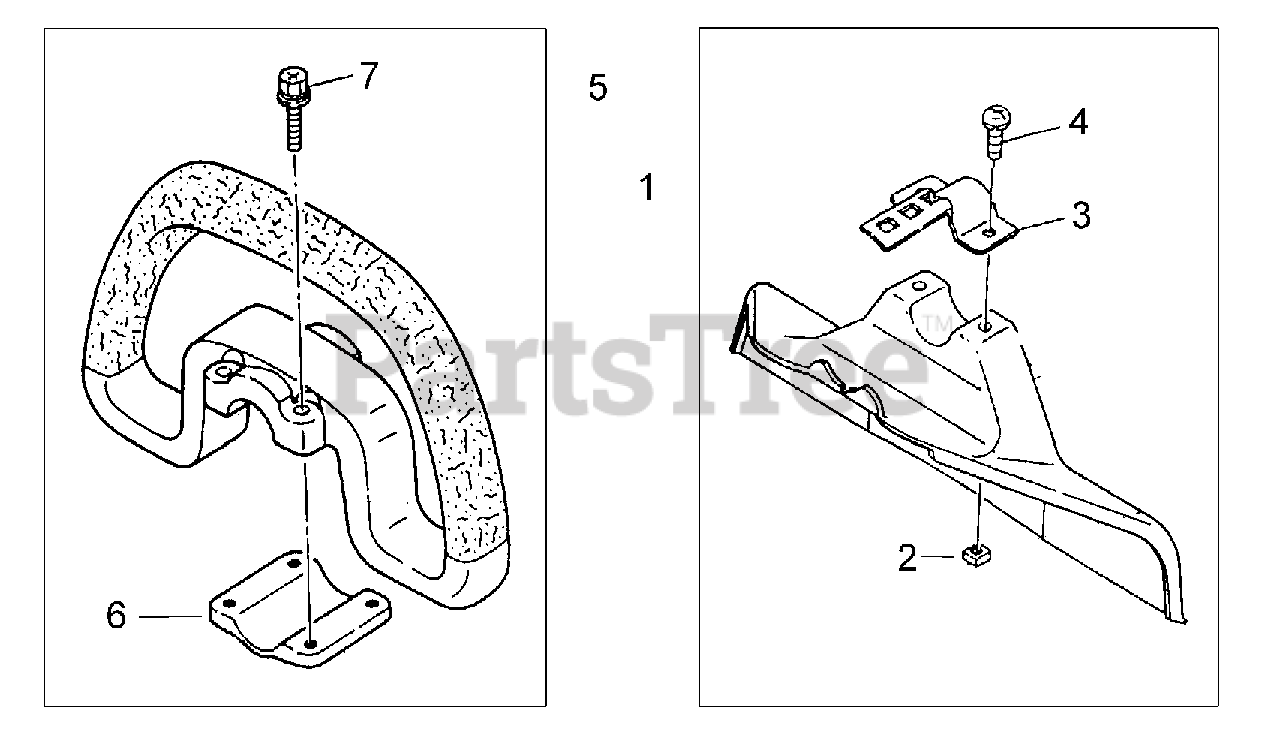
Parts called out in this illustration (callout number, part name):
1	DEBRIS SHIELD KIT - BLACK
2	NUT
3	GUARD, CLAMP
4	SCREW - 5X16
5	HANDLE ASSY
6	CLAMP - A
7	BOLT
